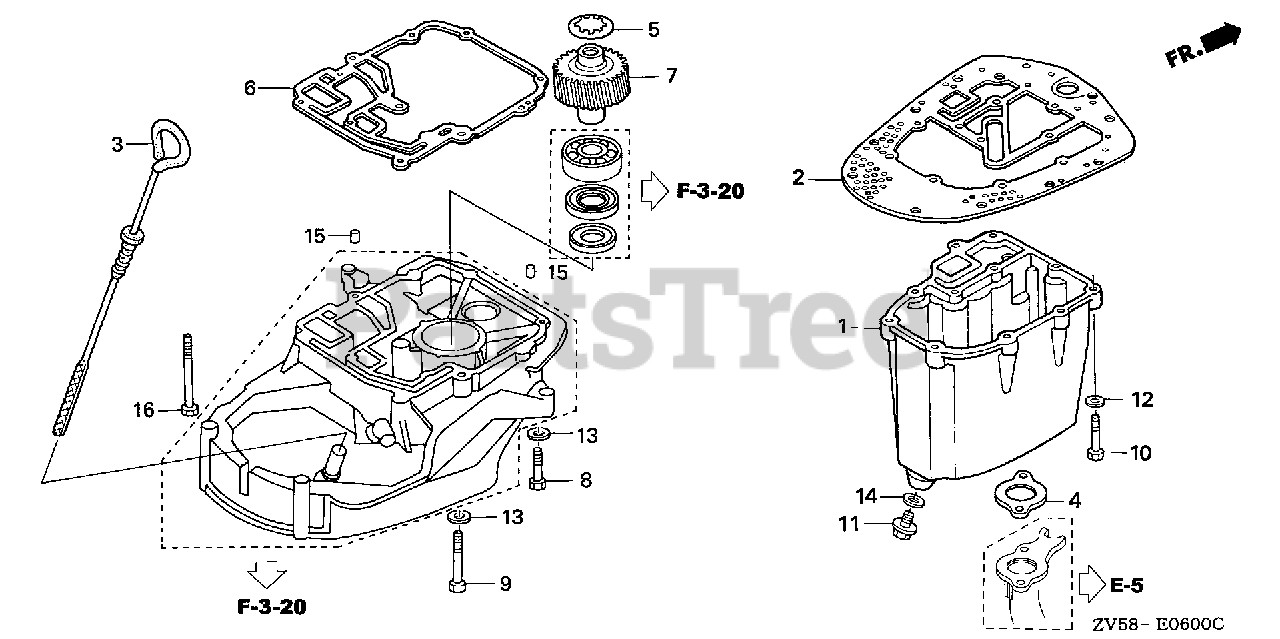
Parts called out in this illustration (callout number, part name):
1	PAN, OIL *TGRAY* (GRAY)
2	GASKET, OIL PAN
3	DIPSTICK, OIL
4	GASKET, EX. PIPE
5	SPRING, THRUST
6	GASKET, PRIMARY GEAR CASE
7	GEAR, PRIMARY DRIVEN (33T)
8	BOLT, HEX. (8X35)
9	BOLT, HEX. (8X55)
10	BOLT, HEX. (6X25)
11	BOLT, DRAIN PLUG
12	WASHER, PLAIN (6MM)
13	WASHER, PLAIN (8MM)
14	WASHER, DRAIN PLUG (12MM)
15	PIN, DOWEL (6X10)
16	BOLT, FLANGE (8X75)
